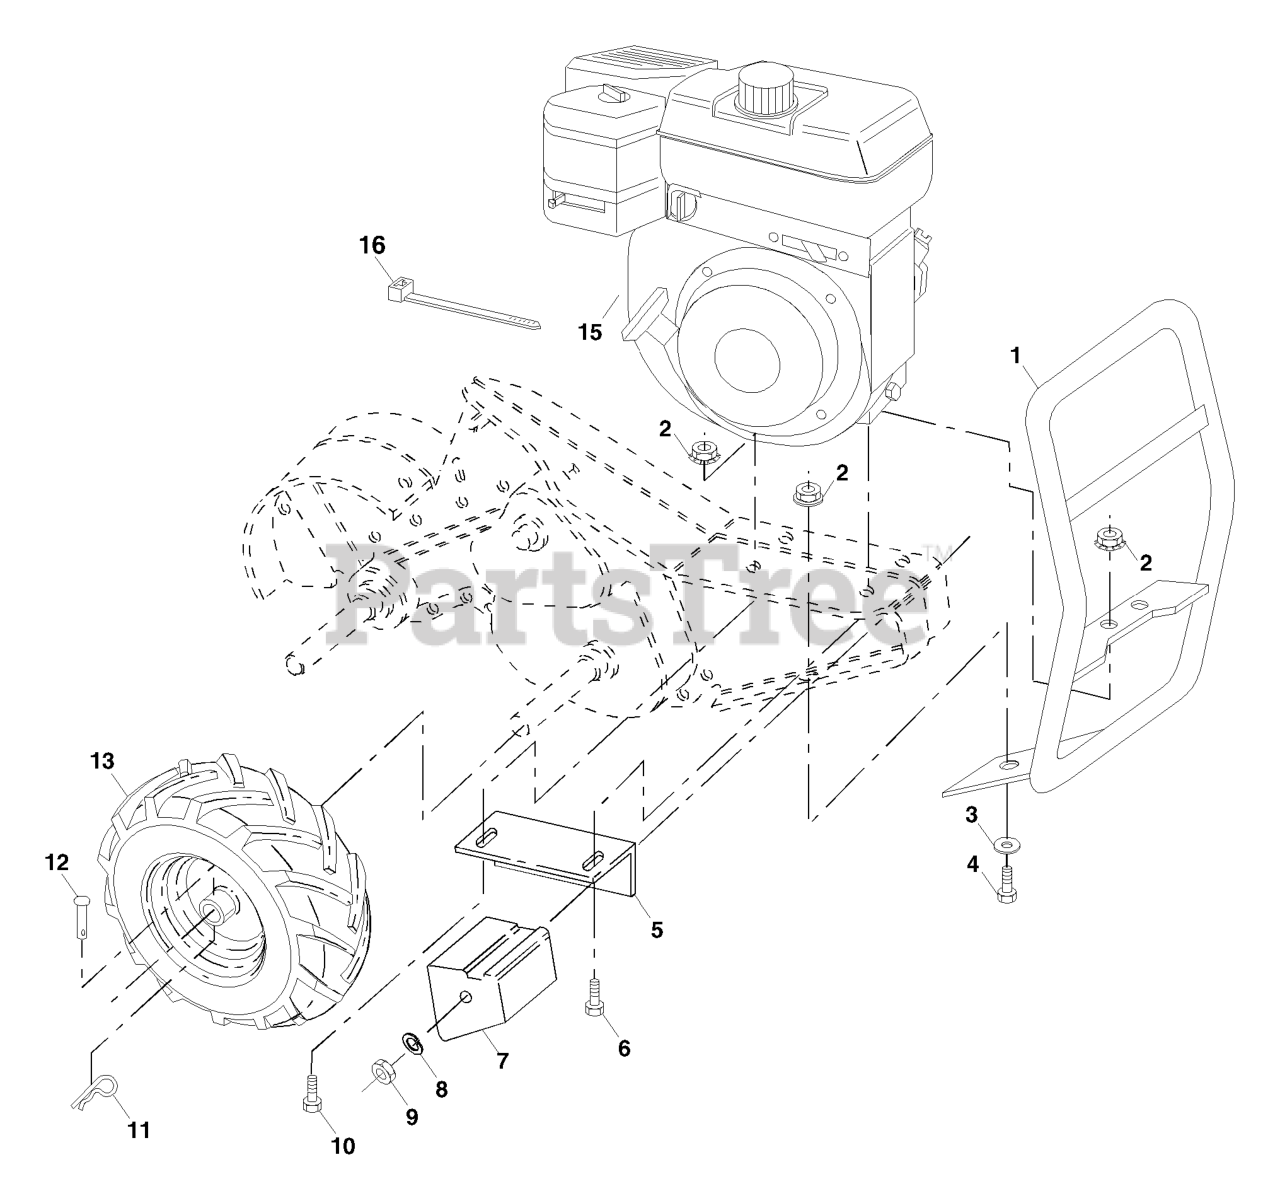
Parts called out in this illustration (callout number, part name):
1	BUMPER
2	LOCKNUT-FLANGE 5/16-18
3	WASHER
4	BOLT
5	DNO BRACKET RH CRT
6	Bolt, Hex 5/16-18 x 2
7	COUNTERWEIGHT, RH
8	WASHER, LOCK 3/8
9	NUT.HEX.3/8-16UNC
10	BOLT
11	RETAINER M
12	RIVET,DRILLED
13	TIRE.16X4-8.CHEVRON.TILLER
13	RIM
13	VALVE STEM LT
15	Engine
16	TIE GUIDE
